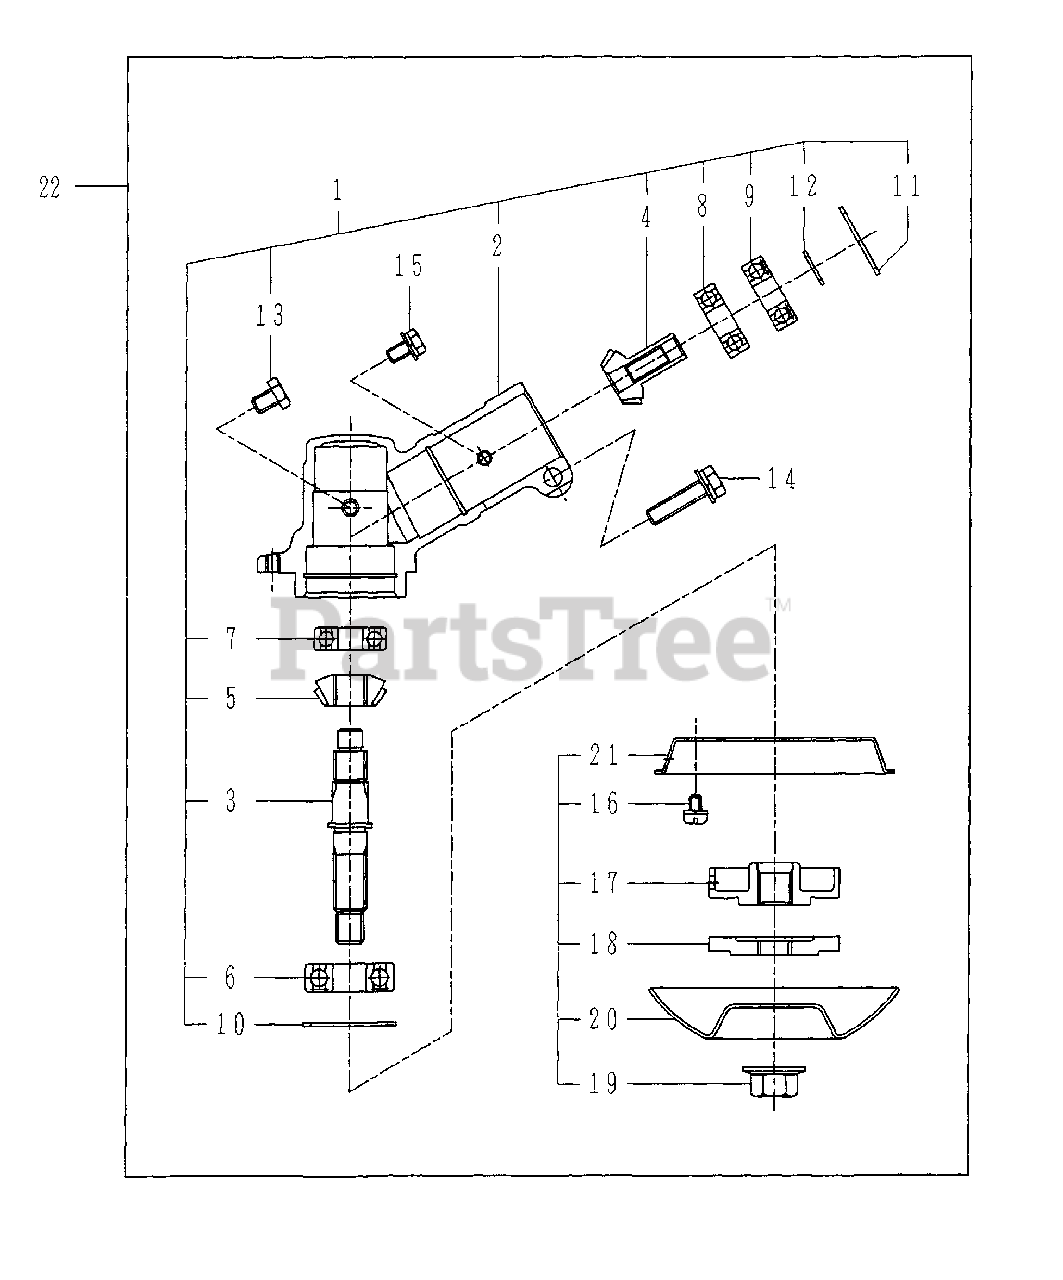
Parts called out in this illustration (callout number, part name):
1	GEAR CASE ASSY
2	HOUSING, GEAR CASE
3	SHAFT, GEAR
4	PINION, BEVEL
5	GEAR, BEVEL
6	BEARING, BALL
7	BEARING, BALL
8	BEARING, BALL
9	BEARING, BALL
10	RING, SNAP
11	RING, SNAP
12	RING, SNAP
13	BOLT
14	BOLT
15	BOLT
16	BOLT
17	PLATE, ADAPTOR - UPPER
18	PLATE, ADAPTOR - LOWER
20	GUARD, BOLT
21	COVER, GRASS
22	CASE KIT, GEAR
